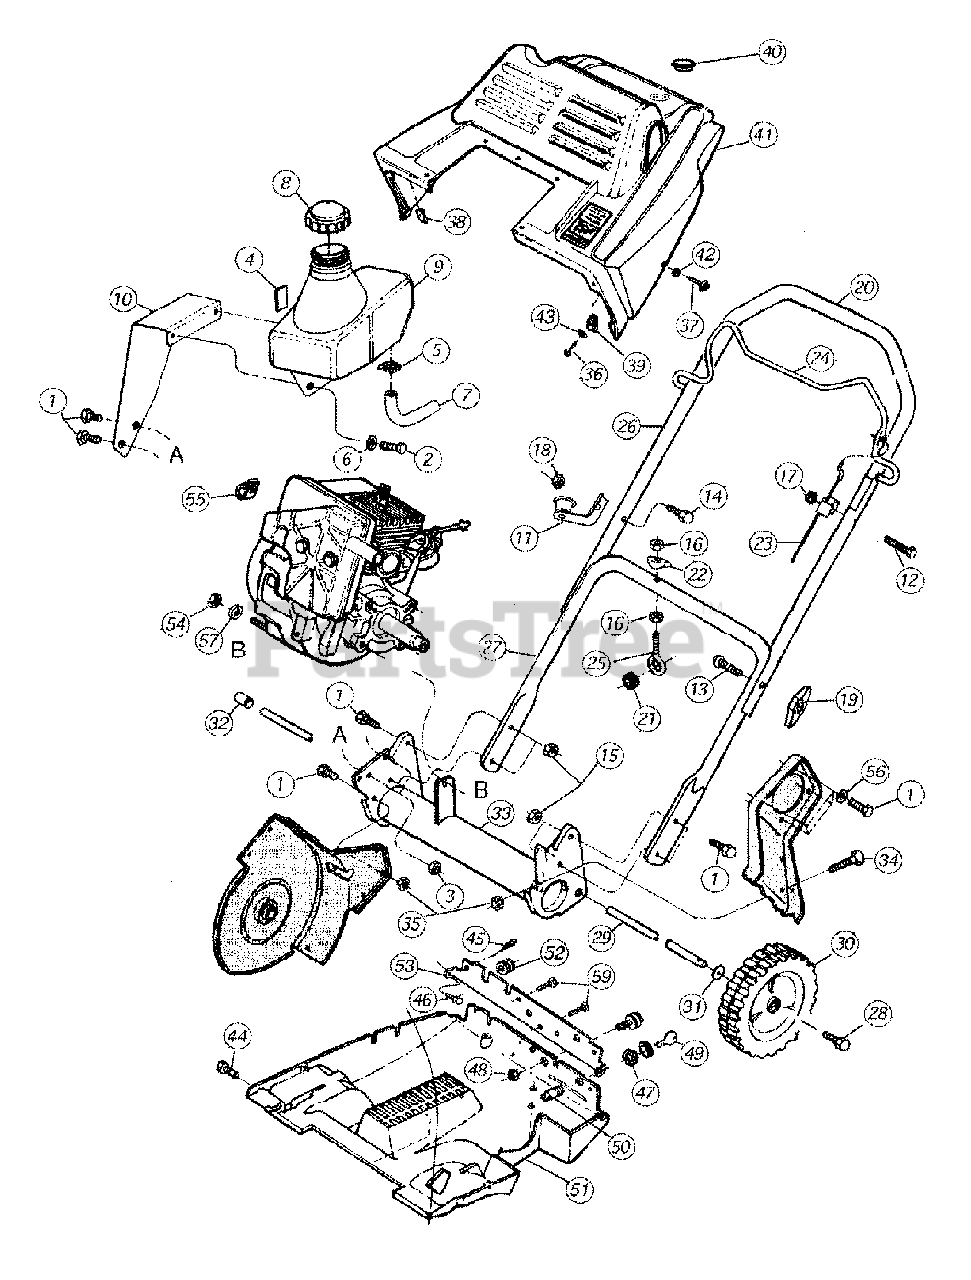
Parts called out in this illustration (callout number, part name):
1	Hex Screw: 5/16 - 18 x .75 Gr 2
2	Hex Screw: 1/4 - 14 x .625
3	Sems Nut
4	Foam Strip
5	Hose Clamp 1/2" OD
6	Flat Washer
7	Hose, Fuel Line
8	Fuel Tank Cap
9	Fuel Tank
10	Support Bracket
11	Bracket Assembly, Rope Guide
12	Hex Screw: 1/4 - 20 x 2.0 Gr 5
13	Carriage Bolt: 5/16 - 18 x 2.0 Lg. Carved
14	Oval C-Sunk Screw
15	Sems Nut
16	Hex Nut: 5/16 - 18
17	Sems Nut 1/4 - 20
18	Top Lock Nut 1/4 - 20
19	Knob Assembly
20	Foam Grip, Handle
21	Grommet: .44 ID x .94 OD x .50
22	Side Lock Washer
23	Drive Cable, Auger
24	Auger Bail, Drive Dipped
25	Eye Bolt 5/16 - 18
28	Tap Screw: 3/8 - 16 x .5
29	Axle, Tube
30	Wheel Assembly
31	Flat washer: .510 ID x .75 OD x .03
32	Spacer
33	Frame Assembly
34	Hex Cap Screw: 5/16 - 18 x 1.00
35	Sems Nut
36	Hex Screw
37	Ab Screw
38	Retainer Clip, U-Style
39	U Nut
40	Snap-In Plug
41	Upper Engine Cover: Oyster Gray 662
42	Flat Washer
43	Flat Washer
44	Hex Screw: 1/4 - 20 x .625
45	Tap Screw: 10 - 24 x .75
46	Tap Screw: 10 - 25 x .75
47	Jam Nut: 5/8 - 32 x .12
48	Sems Nut 1/4 - 20
49	Ignition Key
50	Recoil Starter Key
51	Lower Engine Cover : Oyster Gray 662
52	Grommet: .280 x .750 x .40
53	Control Panel
54	Sems Nut 5/16 - 18
55	Mounting Clamp
56	Lock Washer
57	Flat Washer
58	Tap Screw
59	Cord Assembly
